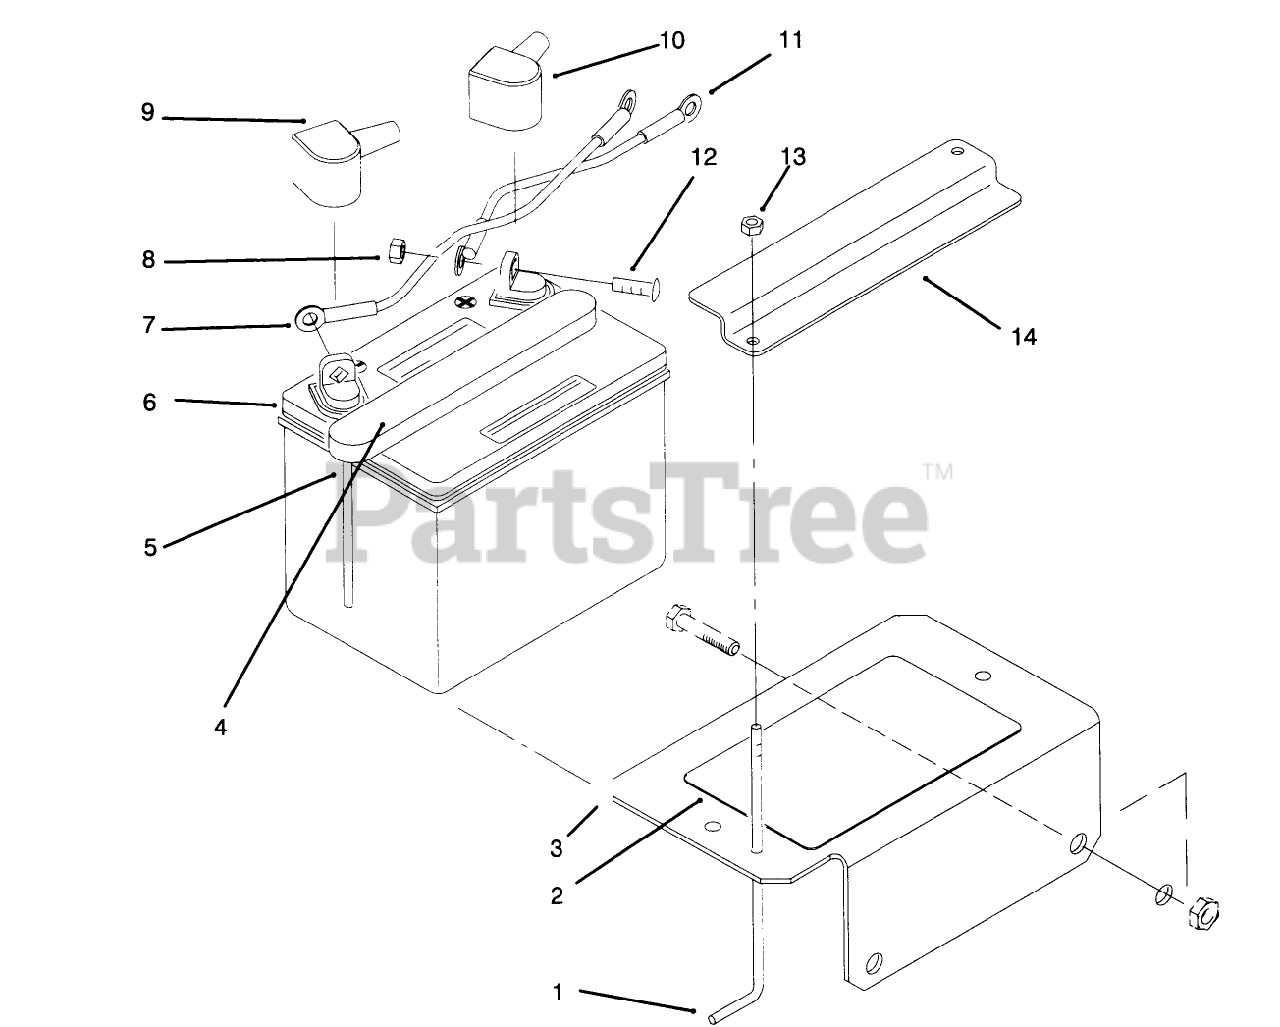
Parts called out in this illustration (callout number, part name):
1	ROD-SUPPORT, BATTERY
2	PAD-SKID, ANTI
3	Holder-Battery
5	TUBE-VENT
6	Battery
7	WIRE ASM
8	NUT-KEPS
9	BOOT-TERMINAL, BLACK
10	BOOT-TERMINAL, RED
11	WIRE-SOLENOID/STARTER
12	SCREW-HH
13	NUT-LOCK, NI
14	Clamp-Battery
